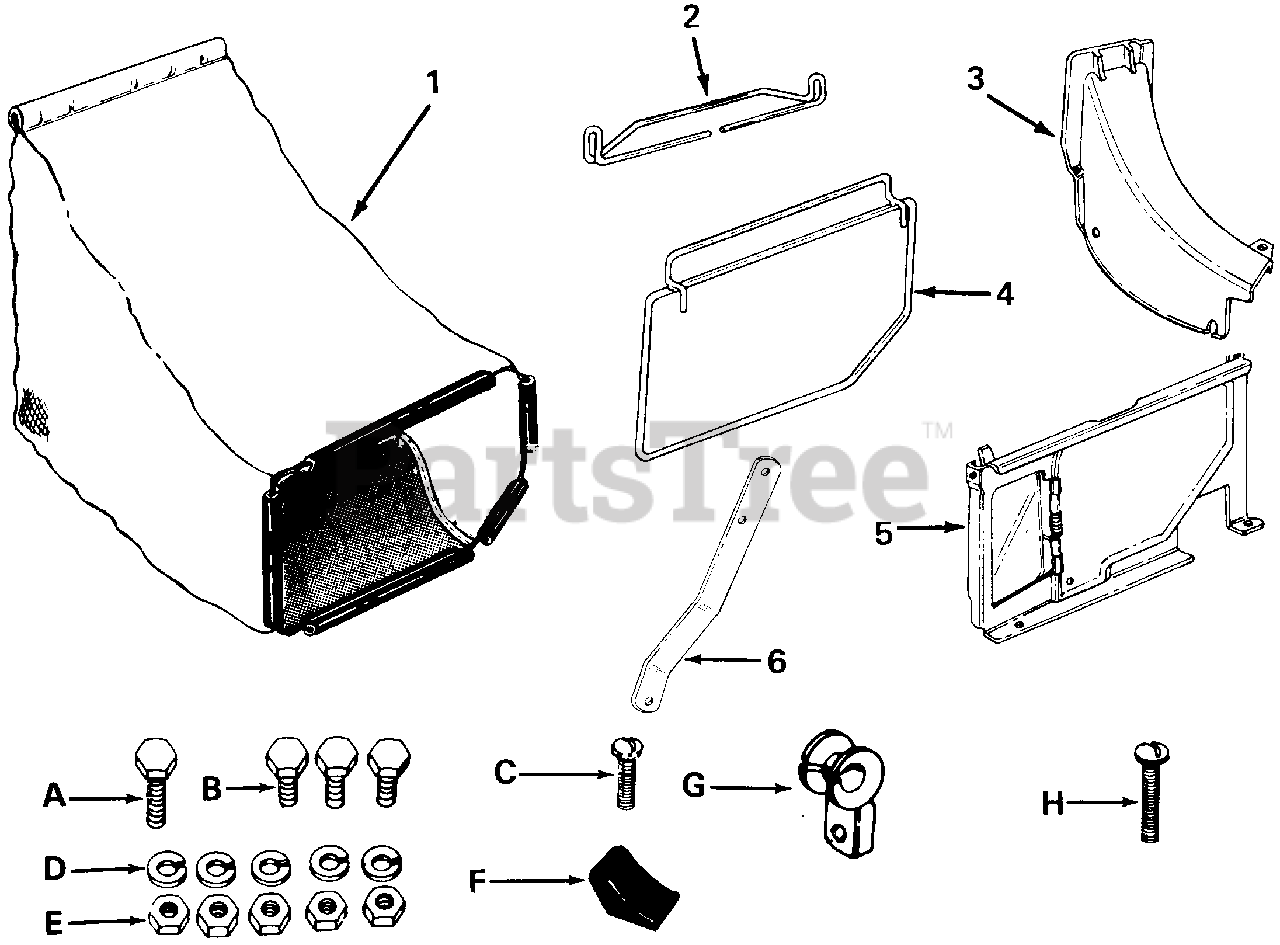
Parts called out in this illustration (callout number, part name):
1	Grass Bag
2	Grass Catcher Handle
3	Top Discharge Chute
4	Front Catcher Frame
5	Top Catcher Panel
6	Panel Support Bracket
A	Hex Bolt 1/4-20 x 5/8" Lg.*
B	Hex Bolt 1/4-20 x 1/2" Lg.* 3
C	Truss Machine Screw 1/4-20 x 1/2" Lg.*
D	Lock Washer 1/4" I.D.* 5
E	Hex Nut 1/4-20 Thread* 5
F	Door Grip
G	Rope Guide
H	Truss Machine Screw 1/4-20 x 1.0" Lg.*
